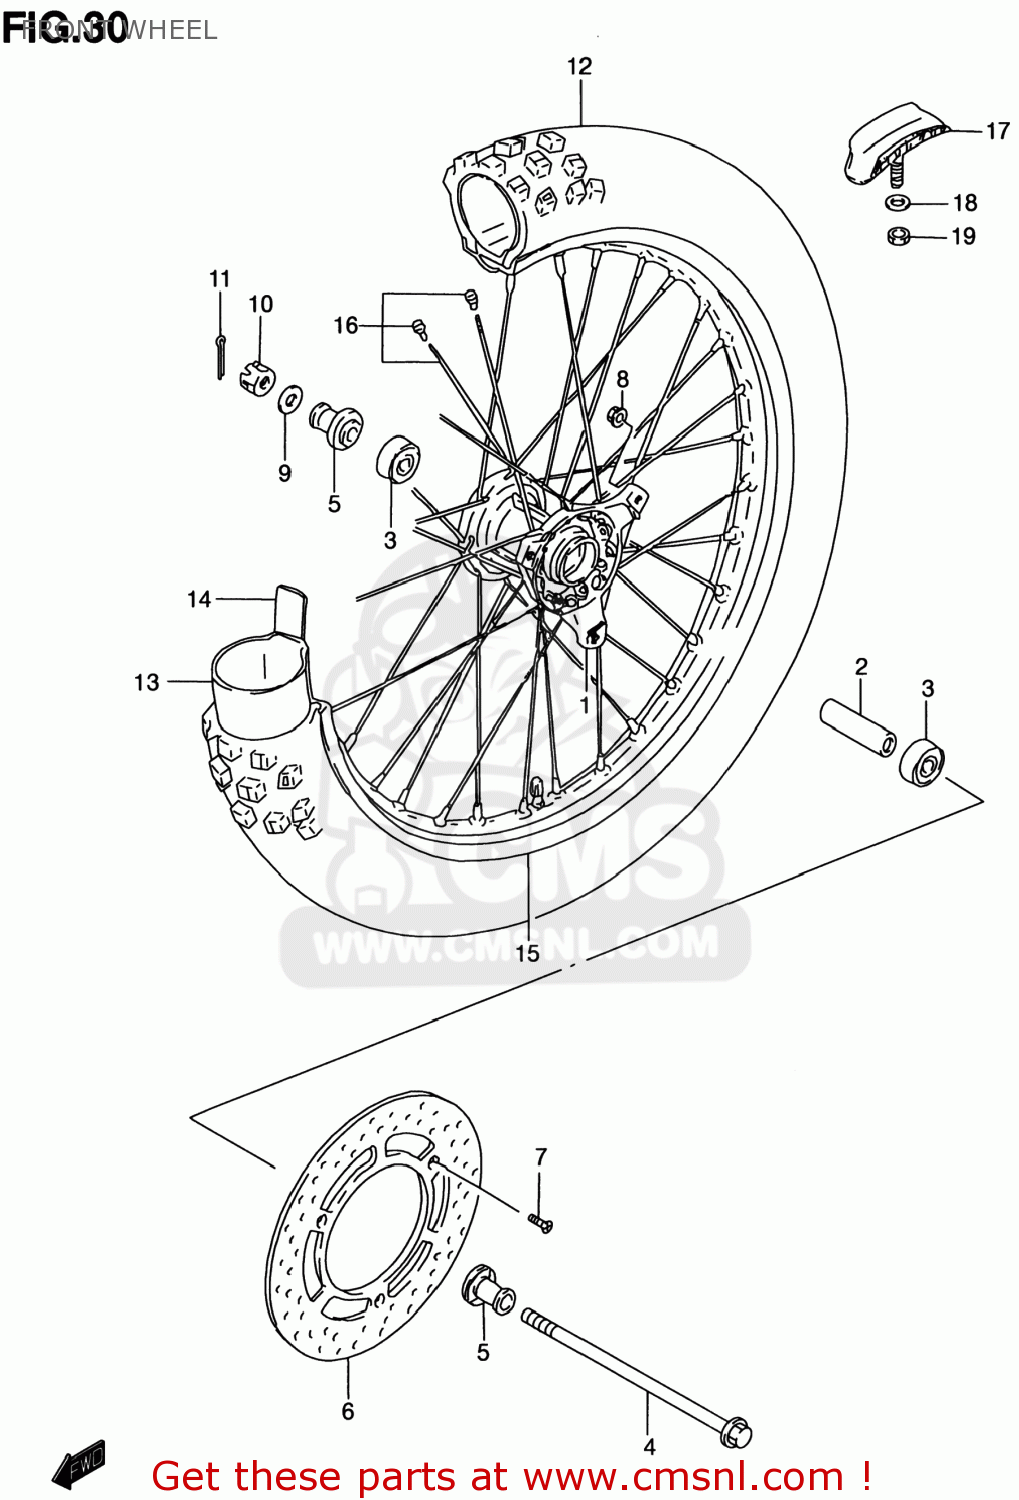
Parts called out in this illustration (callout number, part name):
1	HUB,FR WHEEL
2	SPACER,FR HUB BEARING
3	BEARING (12X32X10)
4	AXLE,FR
5	SPACER,FR AXLE
6	DISC,FRONT BRAKE
7	SCREW(6X22)
8	NUT
9	WASHER
10	NUT,M12X1.25X1
11	PIN 20X20
12	TIRE,FRONT 70/100-17 D
13	TUBE ASSEMBLY,WHEEL,INNER
14	PROTECTOR,WHEEL,INNER
15	RIM,FR WHEEL(1.40X17)
16	SPOKE SET,FR WHEEL
17	STOPPER,BEAD
18	WASHER
19	NUT
